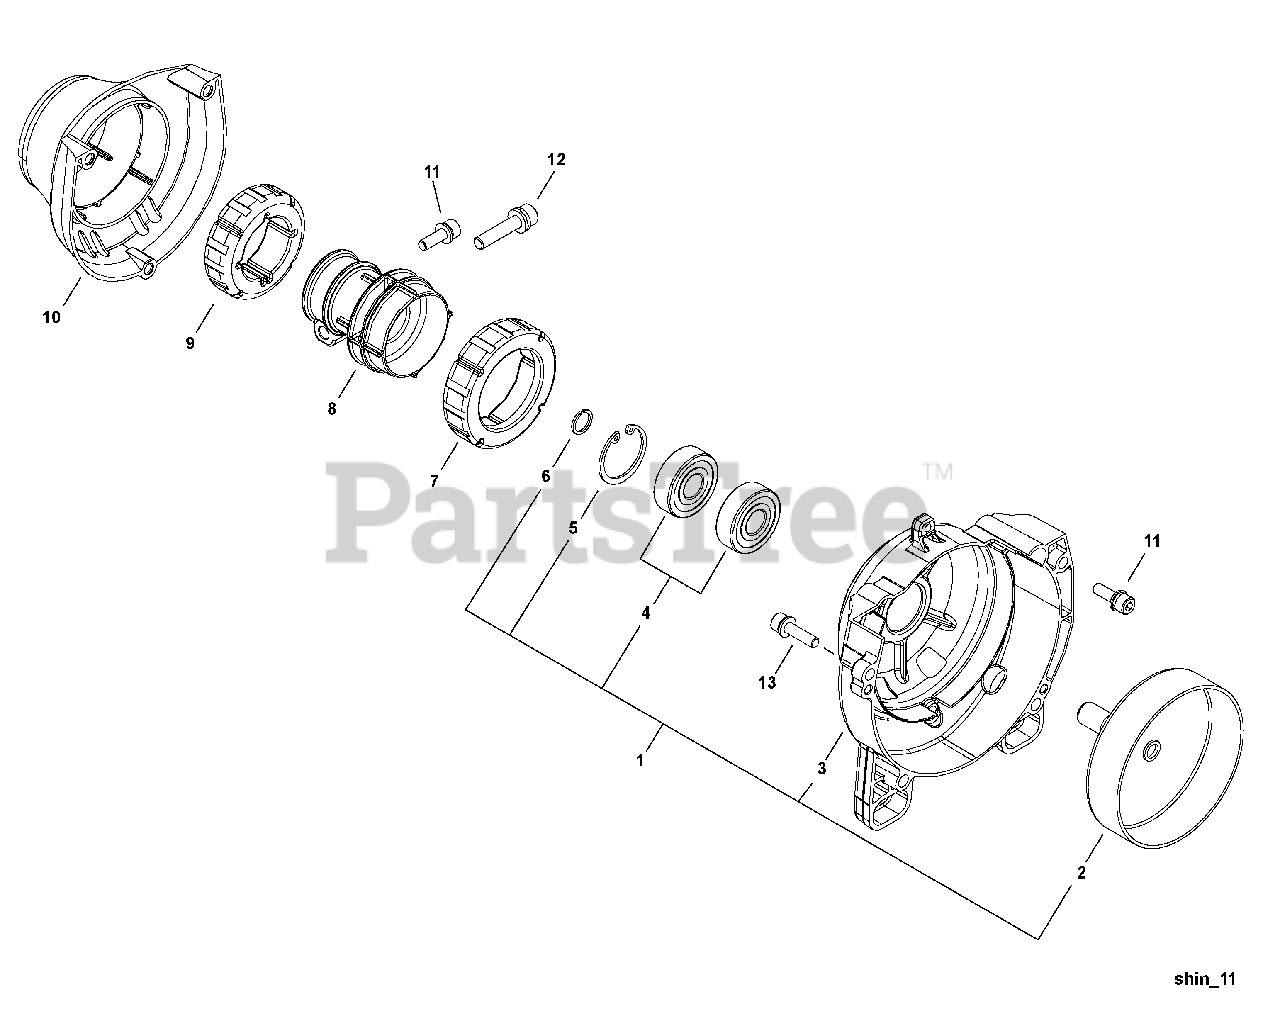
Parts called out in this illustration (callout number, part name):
1	COVER ASSY, FAN
2	DRUM, CLUTCH
3	COVER, FAN
4	BEARING, BALL 6001 DDU C3
5	RING, SNAP Ø28
6	RING, SNAP Ø12
7	HOLDER, REAR CUSHION
8	CUSHION
9	HOLDER, FRONT CUSHION
10	COVER, AV CUSHION
11	BOLT M5×16
12	BOLT M6×28
13	BOLT M5×20
